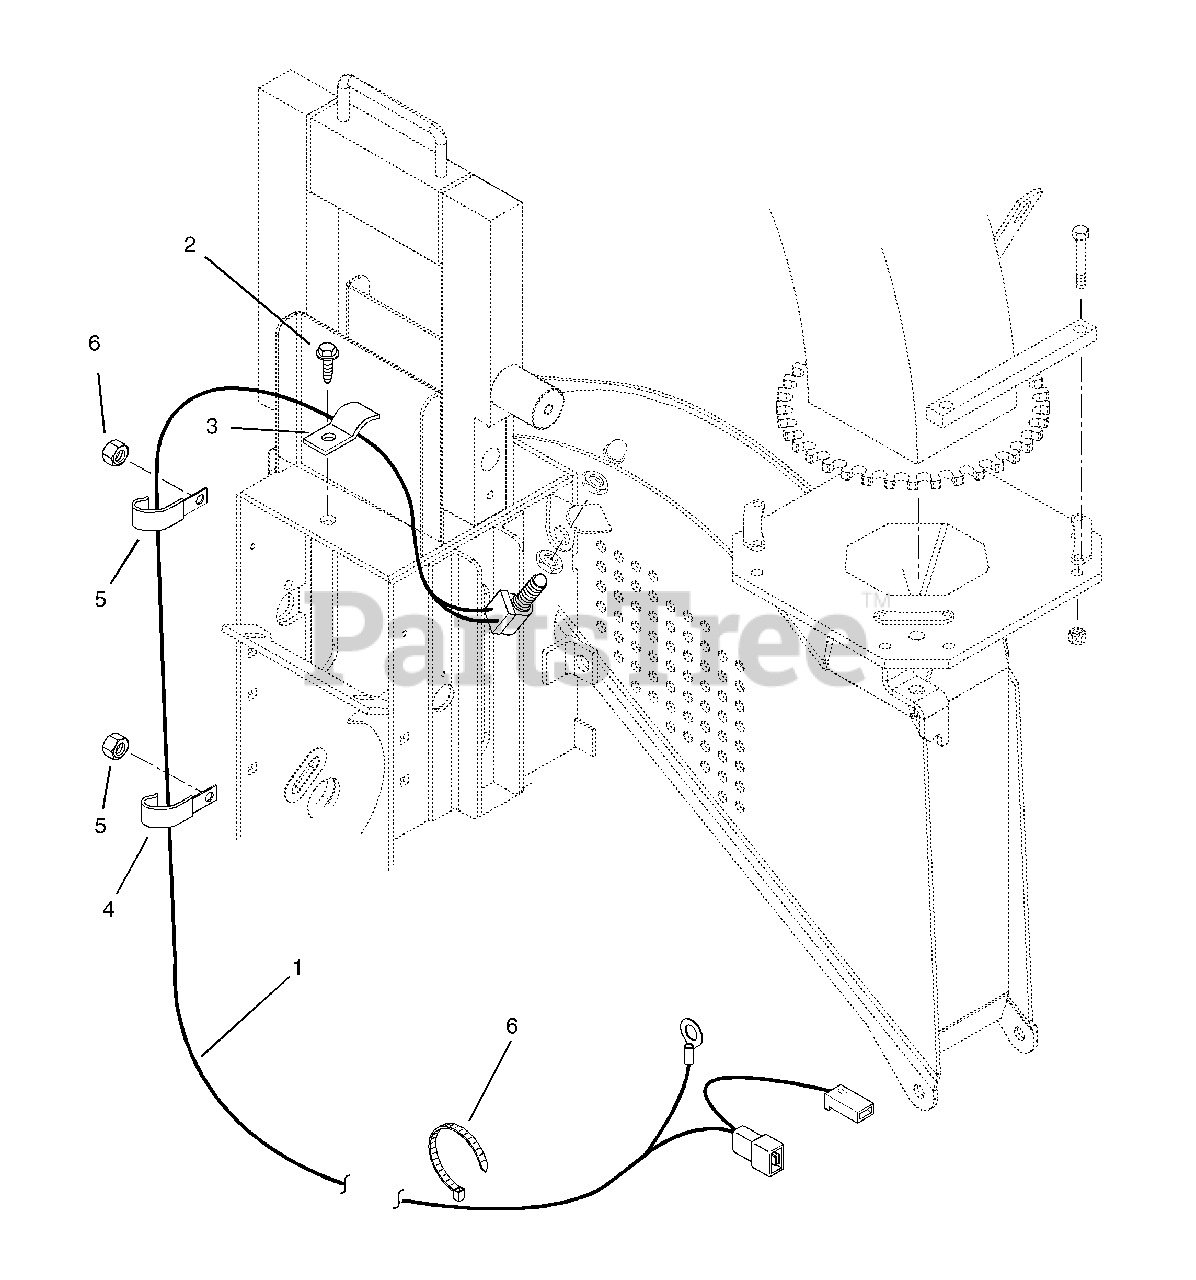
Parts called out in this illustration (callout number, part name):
1	Harness-Wiring 625LR Safety Switch
2	Screw-Tapping .25-20 x .50 Hex Washer Head
5	Nut-Locking-Center .38-16
6	Tie Wrap
